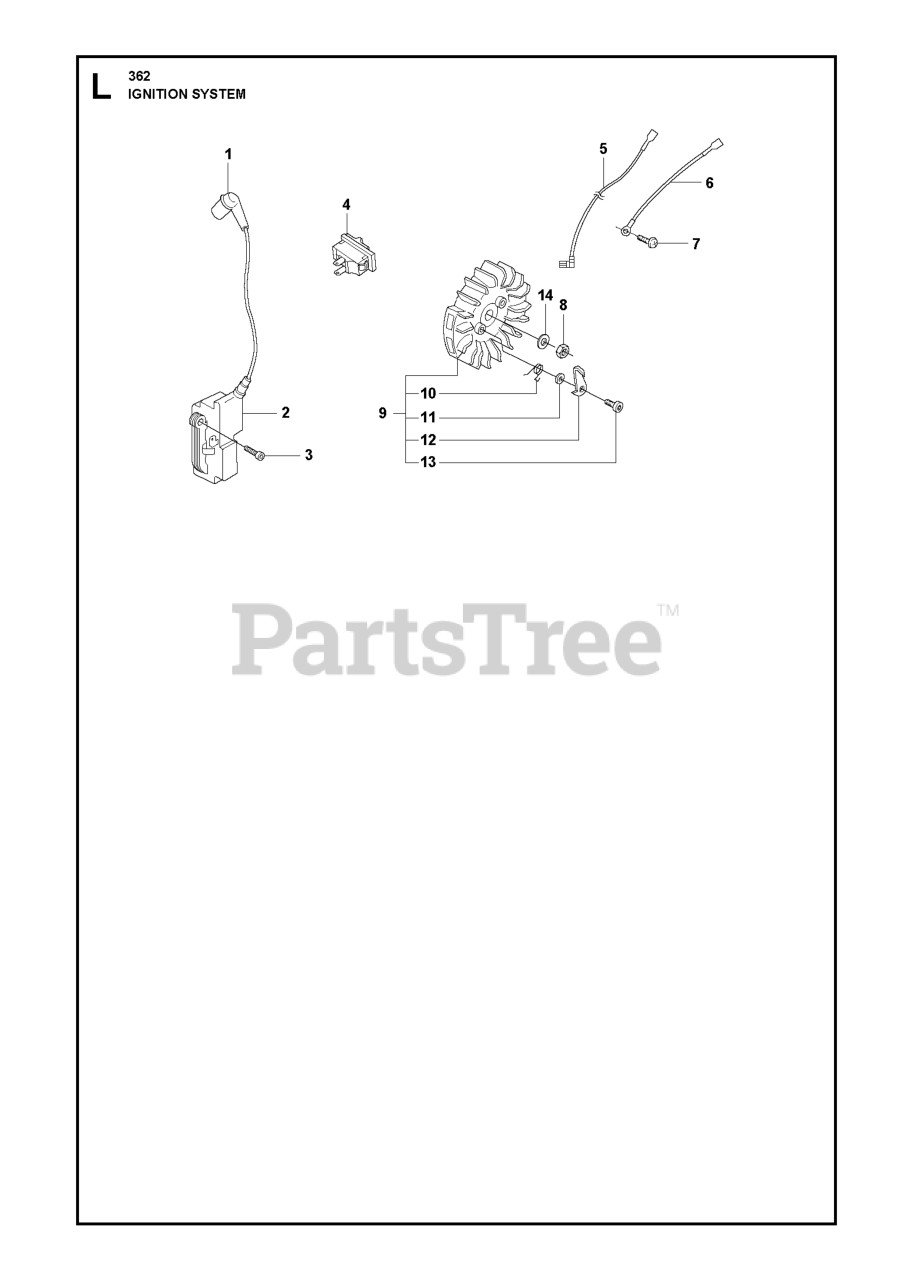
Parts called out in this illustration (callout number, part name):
1	SPARK PLUG CONN. KIT
2	IGNITION MODULE
3	SCREW ITXSCM M5X20 T27 12.9 T
4	START/STOP SWITCH
7	SCREW CITXPANT
13	SCREW
14	WASHER 8.4X16
